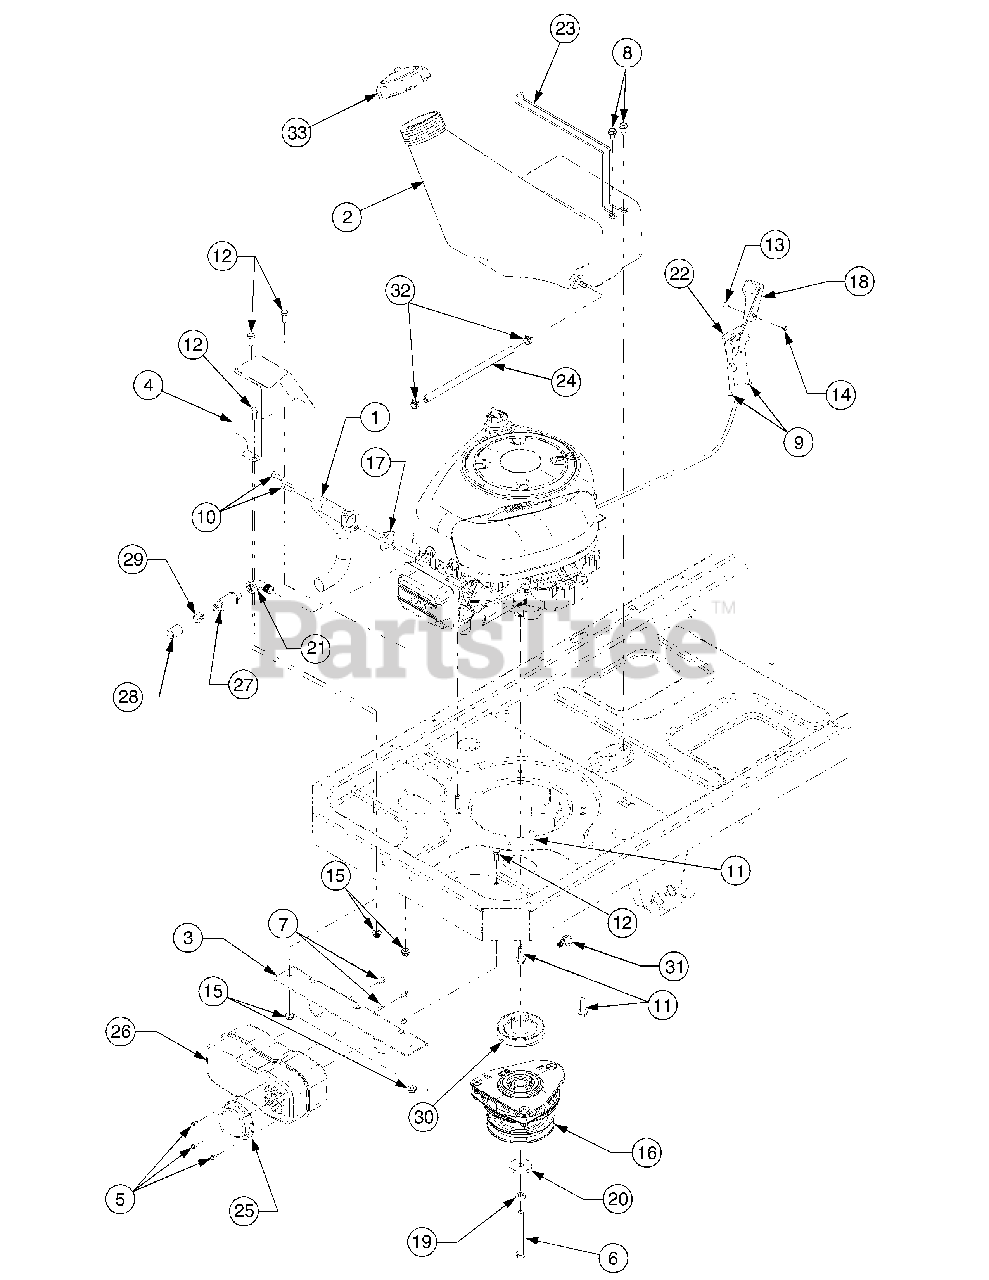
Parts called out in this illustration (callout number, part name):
1	Tube, Exhaust
2	Tank, Fuel, 3.0 Gal.
3	Bracket, Muffler Mounting
4	Shield, Muffler Tube Heat
5	Screw, Hex Wash. Hd. Tapp #8-18 x .5
6	Screw, Hex Cap, 7/16-20 x 4.0 GR5
7	Screw, Hex Wash. Hd. Tapp 1/4-20 x .5
8	Screw, Hex Wash. Hd. Tapp 5/16-12 x .75
9	Screw, Hex Wash. Hd. Tapp #12-16 x .5
10	Screw, Socket Hd. 5/16-18 x .75
11	Screw, Hex Wash. Hd. Tapp 3/8-16 x 1.25
12	Screw, Hex Cap, 5/16-18 x .75 GR5
13	Screw, Truss Hd. Mach. #8-32 x .375
14	Nut, Hex, #8-32
15	Nut, Hx Insert Flange Lck, 5/16-18 GrF
16	Clutch Assembly, Electric PTO
17	Gasket, Exhaust (B&S- 272293)
18	Knob, Throttle Control
19	Washer, Lock, 7/16
20	Washer, Flat, .438 x 1.75 x .25
21	Fitting, Elbow
22	Cable, Throttle, 39.0 Lg
23	Wire, Tank Mounting
24	Hose, Fuel Line 6.5 in
25	Deflector, Muffler
26	Muffler
27	Valve, Oil Drain
28	Hose, Oil Drain Extension
29	Cap, Oil Drain Valve
30	Pulley, Drive
31	Clip, Cable Retainer
32	Clamp, Hose
33	Cap, Fuel
